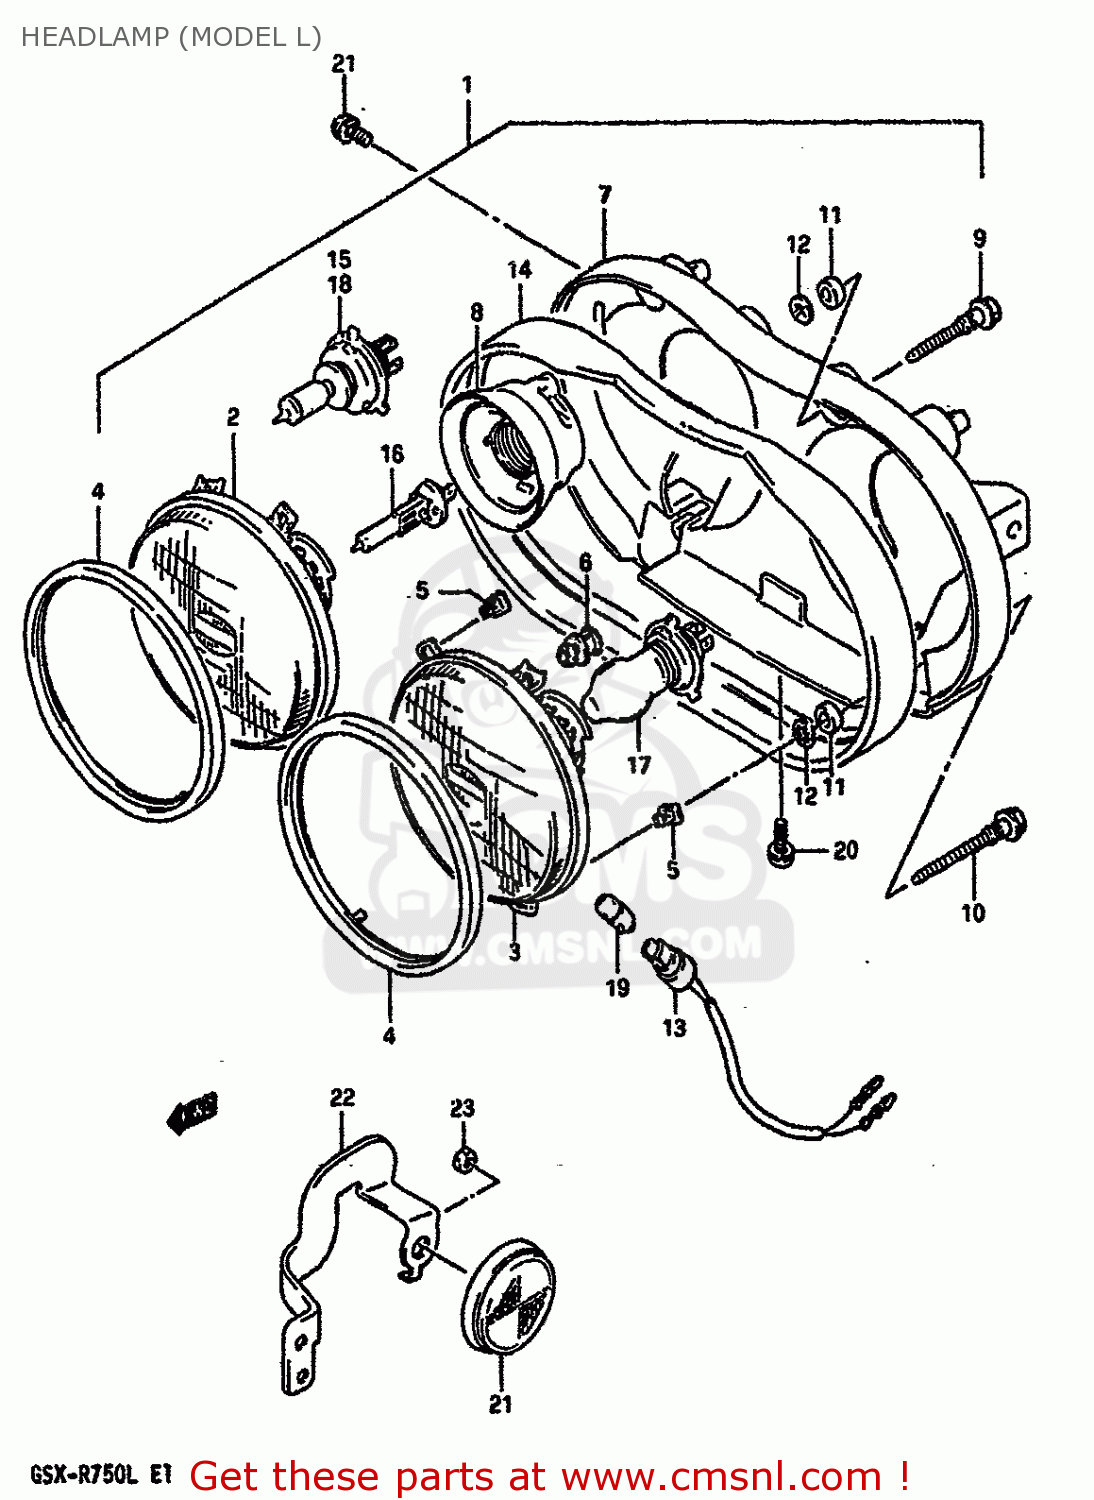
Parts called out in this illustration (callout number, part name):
1	HEADLAMP ASSY
2	UNIT,HEADLAMP RH
3	UNIT,HEADLAMP LH
4	RING,RETAINING
5	NUT,HEADLAMP ADJUSTER
6	SCREW,SPHERICAL
7	HOUSING,HEAD LAMP
8	COVER,SOCKET
9	SCREW,HEADLAMP ADJUST
10	SCREW,ADJUSTER
11	BUSHING
12	WASHER
13	SOCKET
14	GASKET,HEADLAMP
15	BULB(12V60/55W,H4)
16	BULB(12V55W/H1/P14.5S/OSRA,PHI
17	BULB (12V, 60/55W, H4)
18	BULB(12V35/35W)
19	BULB(12V4W)
20	SCREW
21	REFLECTOR,REFLEX FR
22	BRACKET,FR SIDE RR,R
23	NUT
